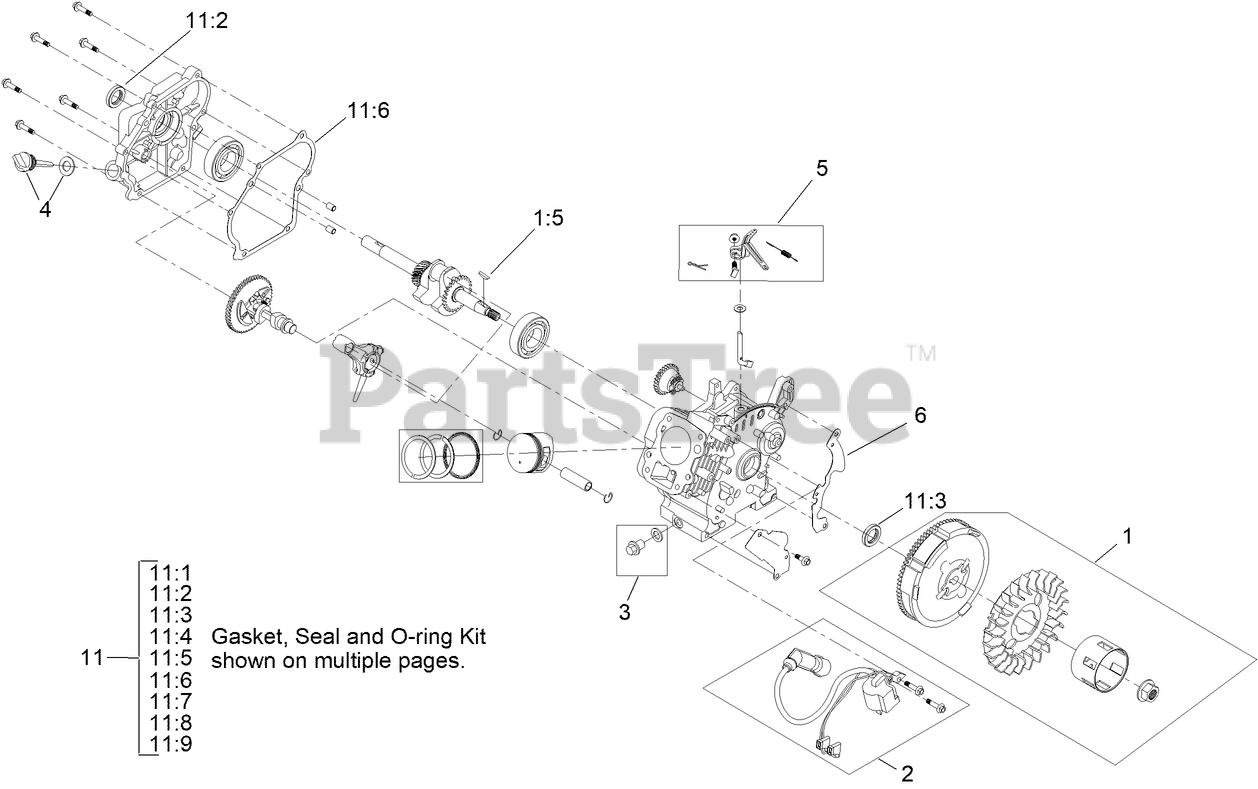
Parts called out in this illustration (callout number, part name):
1	FLYWHEEL AND FAN KIT
1:5	KEY-WOODRUFF
2	IGNITION KIT
3	DRAIN PLUG KIT
4	DIPSTICK AND O-RING KIT
5	GOVERNOR KIT
6	BLOWER SHROUD KIT
11	GASKET, SEAL, AND O-RING KIT
11:1	GASKET-EXHAUST
11:2	SEAL-OIL
11:3	SEAL-OIL
11:4	GASKET-COVER, VALVE
11:5	GASKET-HEAD, CYLINDER
11:6	GASKET-COVER, CRANKCASE
11:7	GASKET-INSULATOR
11:8	INSULATOR-CARBURETOR
11:9	GASKET-CARBURETOR
